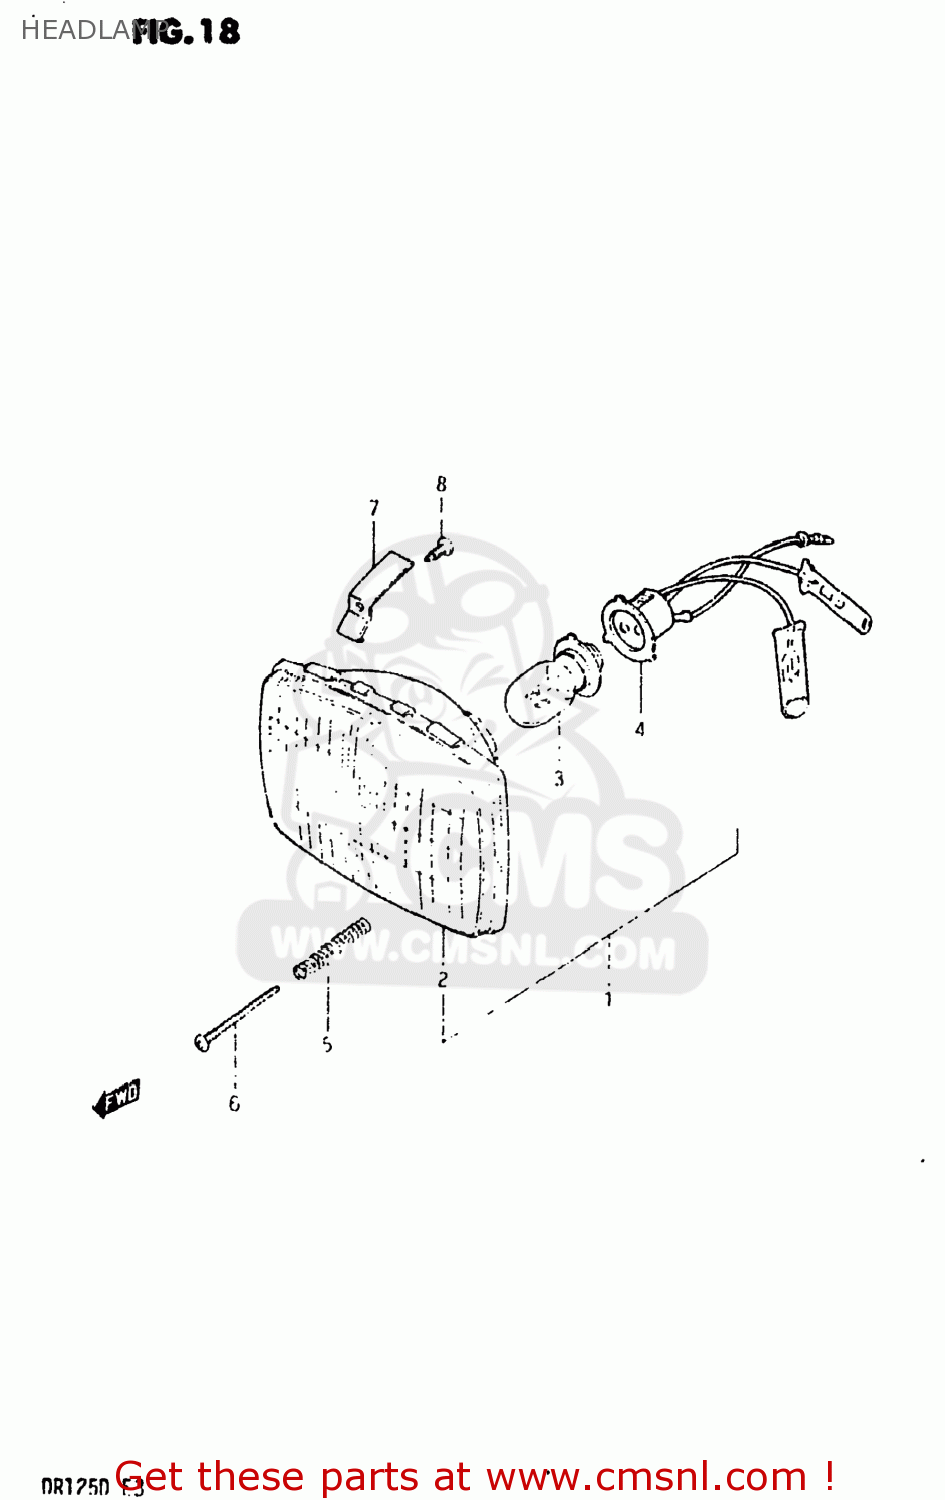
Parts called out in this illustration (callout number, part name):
1	HEADLAMP ASSEMBLY
2	LAMP UNIT
3	BULB(6V15/15W/STANLEY,A3598HA)
4	SOCKET,HEADLAMP
5	SPRING,HEAD LAMP ADJUSTER
6	SCREW,HEADLAMP ADJUST
7	SPRING
8	SPRING,HEADLAMP ADJUST
